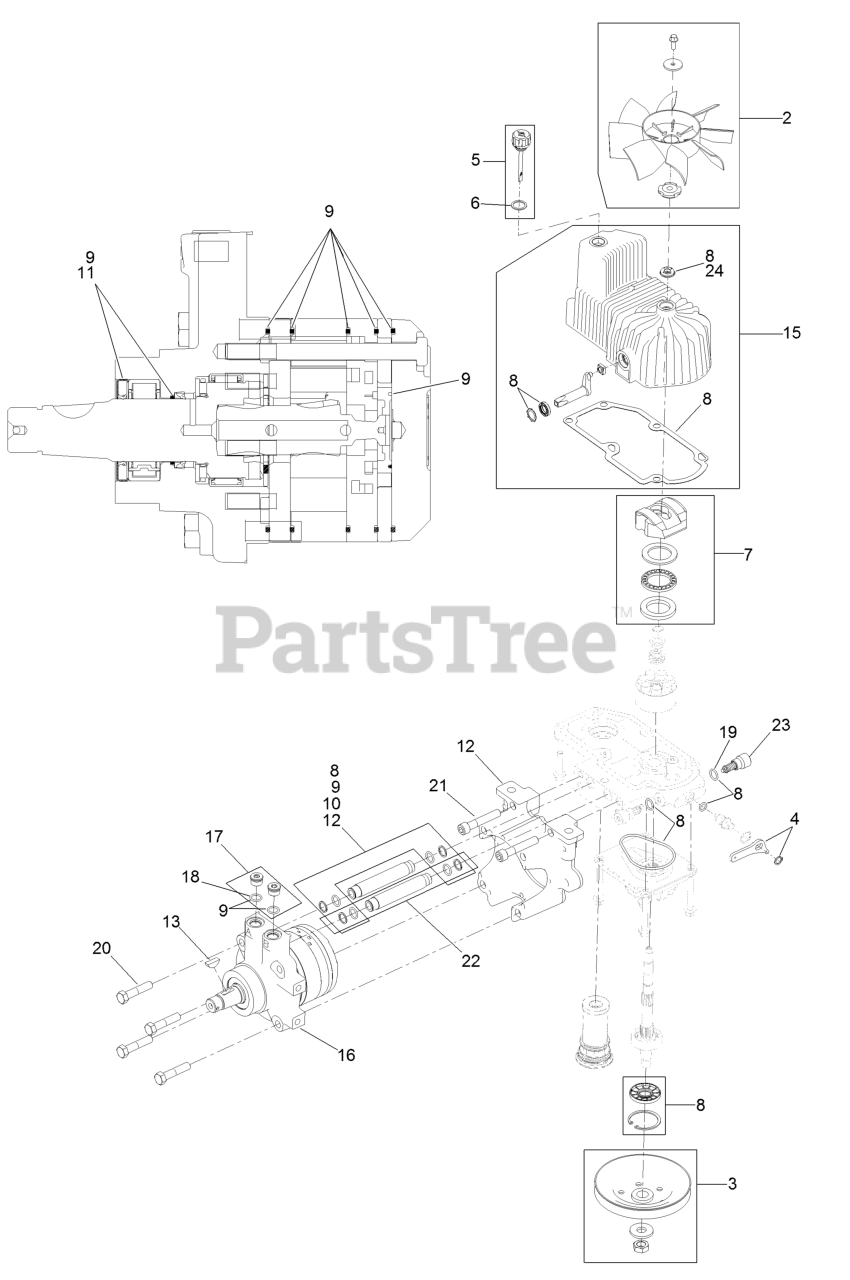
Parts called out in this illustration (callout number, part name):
2	Fan Kit
3	Pulley Kit
4	Handle-Bypass Valve, Hydro
5	Dipstick-Hydro W/Gasket
6	Gasket-Dipstick, Hydro
7	Swash Block Kit
8	Pump Seal Kit
9	Motor Seal Kit
10	Tube Seal Kit
11	Output Shaft Seal Kit
12	Nose Cup-Uht
13	Key-Woodruff
15	Housing-LH
16	Motor-Hydraulic, LH 280Cc
17	Magnetic Plugs Service Kit
19	O-Ring-Check Valve
20	Screw HH
21	Screw-HSH
22	Hydraulic Tube Kit
23	Shock Valve, 16Cc Hydro
24	Seal-Fan Drive
99	Flow Test Kit
